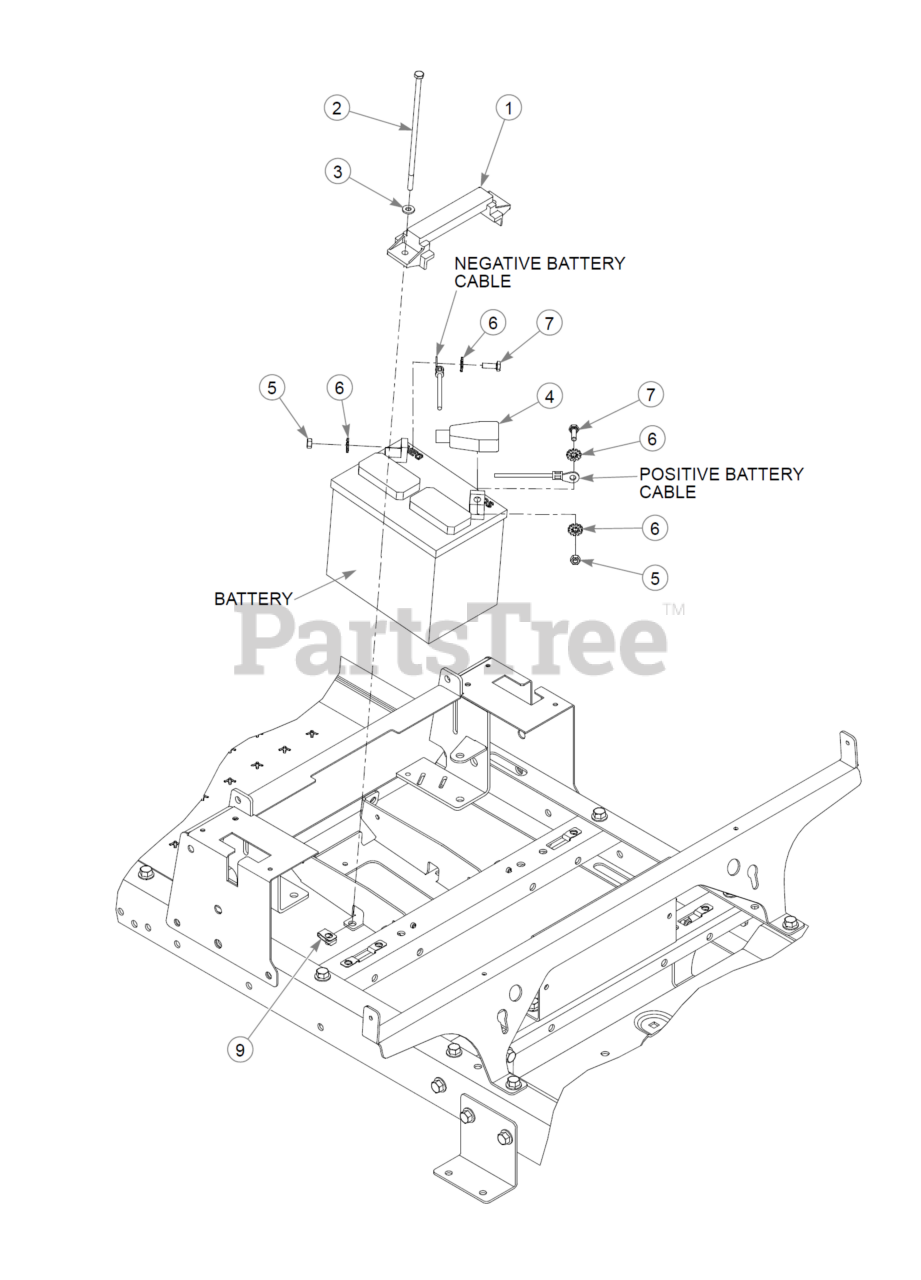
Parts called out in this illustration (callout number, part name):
1	STRAP, TIE DOWN
2	CS .250-20X7.50 HX G5 ZN
3	FW 0.281SAE
4	BATTERY CBL BOOT-RED(FS)
5	NT .250-20HXG5
6	LW .250 INTEXT ZN
7	CS .250-20X0.75 HX G5 ZN
8	WIRE TIE, SMALL/SHORT
9	CN .250-20X .150 MAX THK
